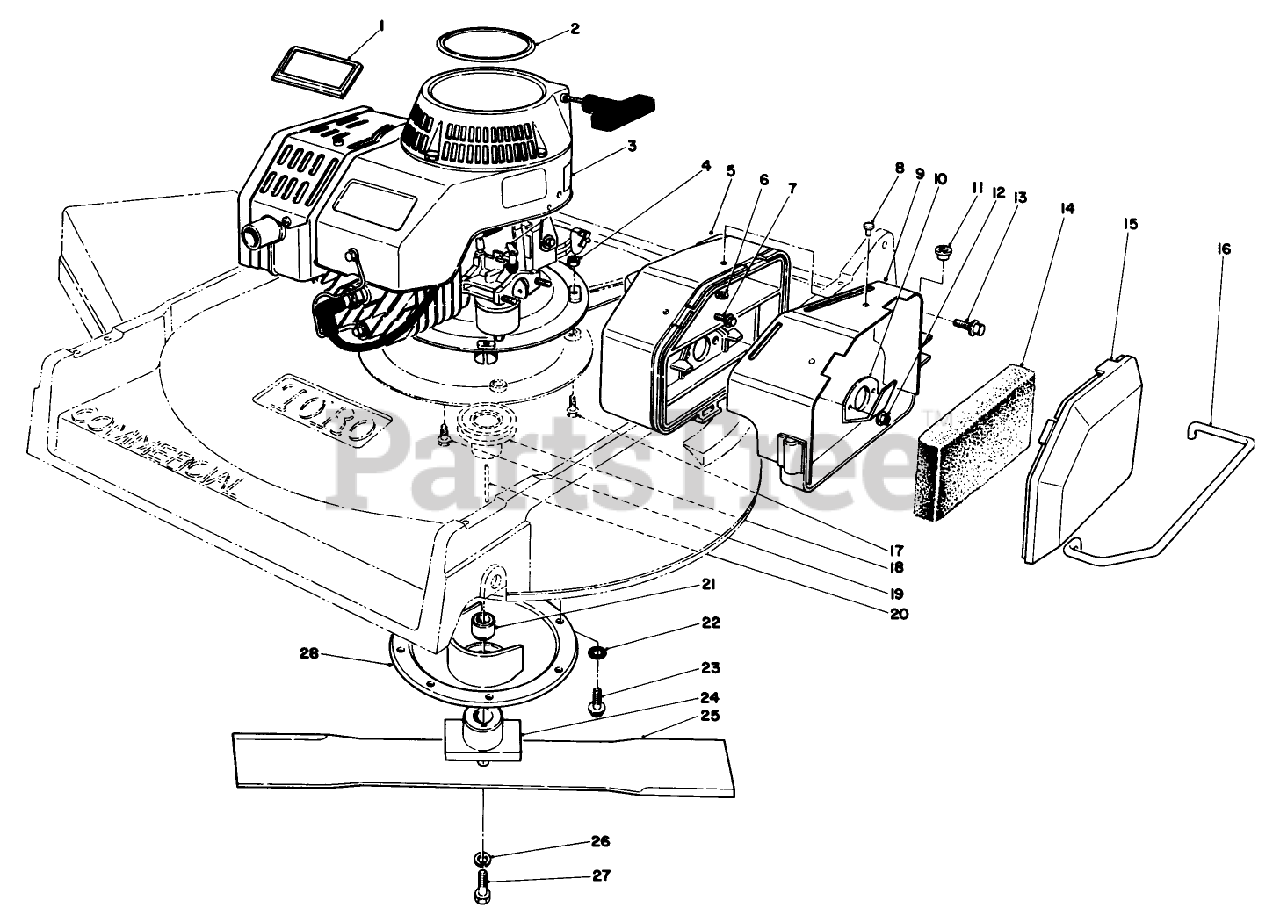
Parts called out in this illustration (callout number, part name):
3	DECAL - FUEL
4	NUT-JAM
5	AIR CLEANER ASM
6	WASHER-FLAT
8	RIVET-POP
10	SPIT BACK DEFLECTOR
13	SCREW-HHF
14	FILTER
16	AIR CLEANER GUARD*
17	SCREW-HH
18	PULLEY-DRIVER
19	SCREW-HH
20	KEY-SQUARE
21	BLADE SPACER
22	WASHER-LOCK, INTERNAL
23	SCREW-HWHTF
25	BLADE
26	WASHER-LOCK
27	SCREW-BLADE
